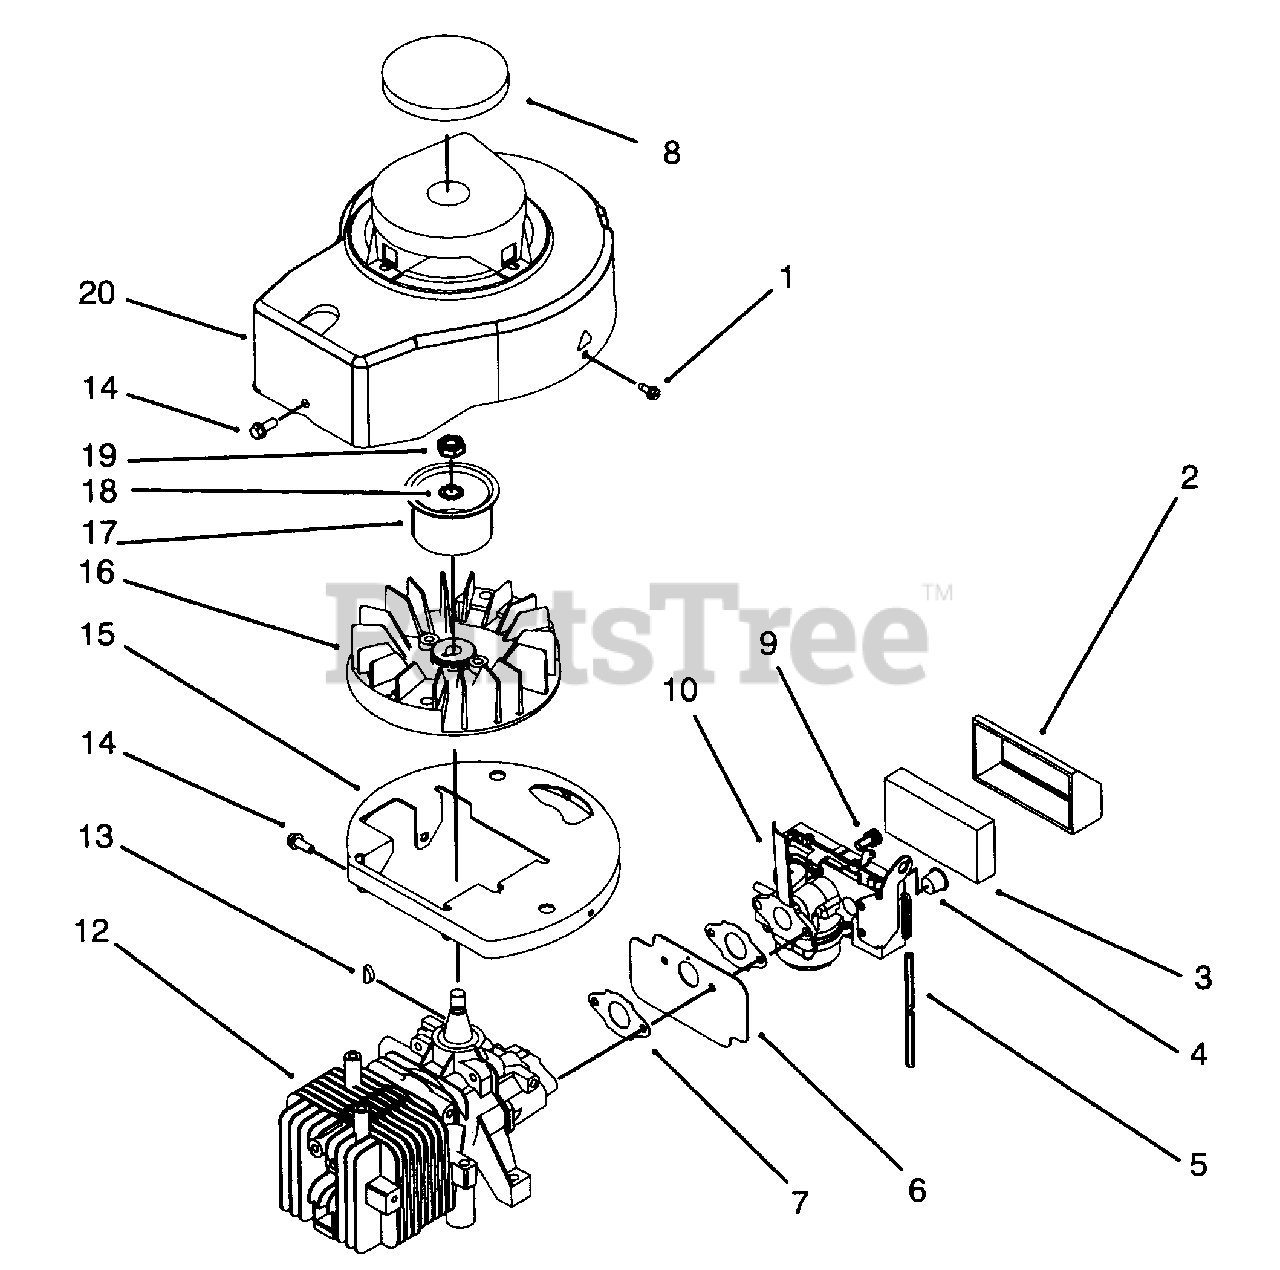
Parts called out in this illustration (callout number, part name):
2	Cover-Air Filter
3	Element-Air Filter
4	Plug
5	Hose-Primer
6	Shield-Carburetor
7	Gasket-Carburetor
8	Disc-Foam
10	Carburetor Assembly
12	Short Block Assembly
14	Screw
15	Base-Shroud
16	Flywheel Assembly
17	Hub-Starter
18	Washer-Lock
20	Shroud
